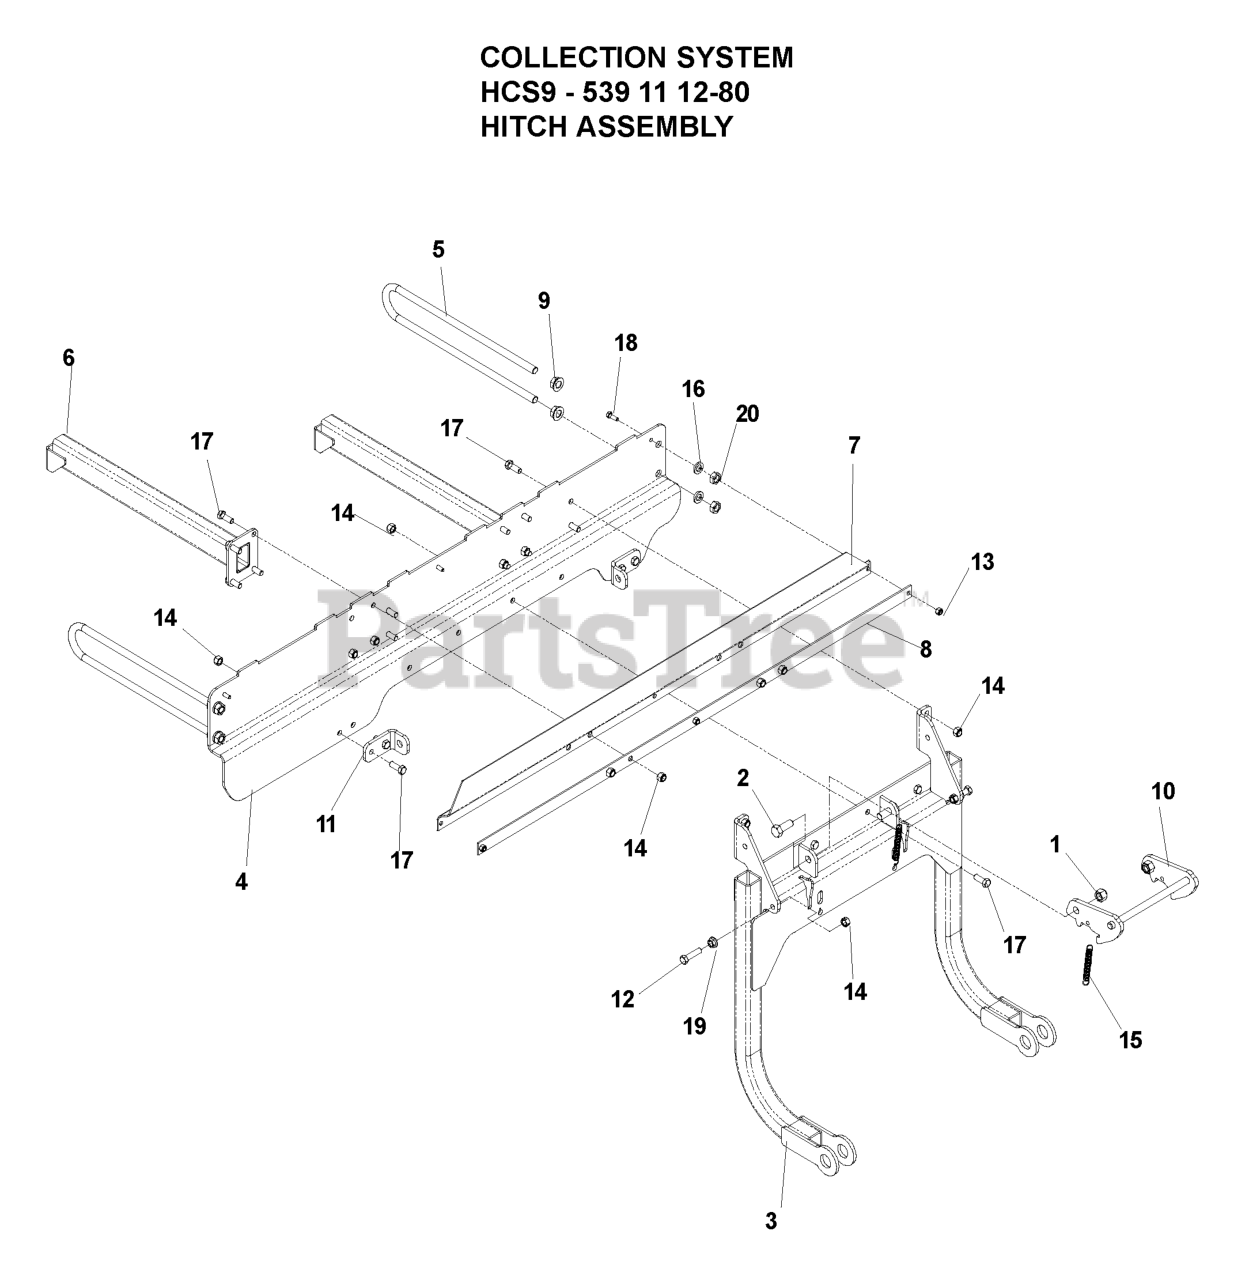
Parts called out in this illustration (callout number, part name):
1	NUT, 1/2-13, NYLOC
2	HCS, 1/2-13 X 1 1/4, GR5
4	MOUNT Z BRACE
5	SUPPORT, OUTER
6	SUPPORT ARM
7	SEAL, RUBBER
8	SEAL STRAP
9	NUT, 1/2-13, WHIZLK, GR5
11	BRACKET, SUPPORT
12	HCS, 3/8-16 X 1 1/2, GR5
13	NUT, 1/4-20, NYLOC
14	NUT, 3/8-16, NYLOC
16	LOCKWASHER, 1/2
17	HCS, 3/8-16 X 1, GR5
18	HCS, 1/4-20 X 3/4, GR5
19	NUT, 3/8-16, WHIZLK
20	NUT, 1/2-13, JAM
539111280	Hitch Assembly Collection System
